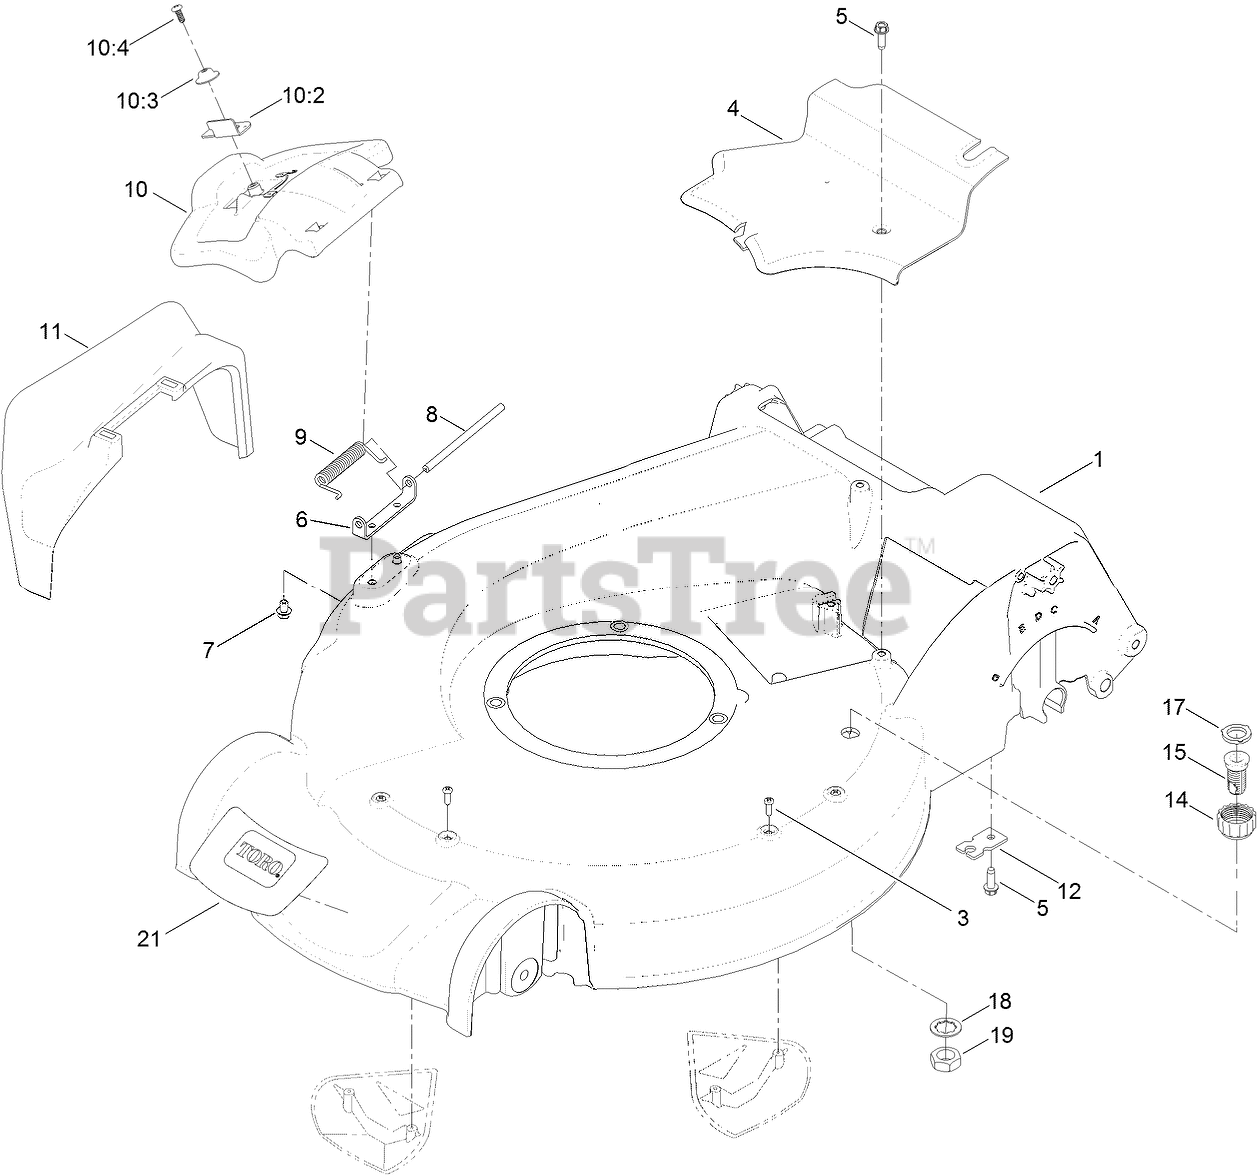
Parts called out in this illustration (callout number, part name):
1	HOUSING ASM
3	SCREW-PPH
4	COVER-BELT
5	SCREW-HWHTF
6	BRACKET-COVER
7	SCREW-HWH
8	ROD-COVER
9	SPRING-TORSION
10	DISCHARGE DOOR ASM
10:2	LATCH-DOOR
10:3	CAP-DOOR
10:4	SCREW-PLASTITE
11	CHUTE-DISCHARGE, SIDE
12	BRACKET-CABLE, TRACTION
14	COUPLING-HOSE, WASHOUT PORT
15	PORT-WASHOUT
17	WASHER-SEAL, WASHOUT PORT
18	WASHER-TOOTH, INTERNAL
19	NUT-JAM
21	DECAL-DECK
